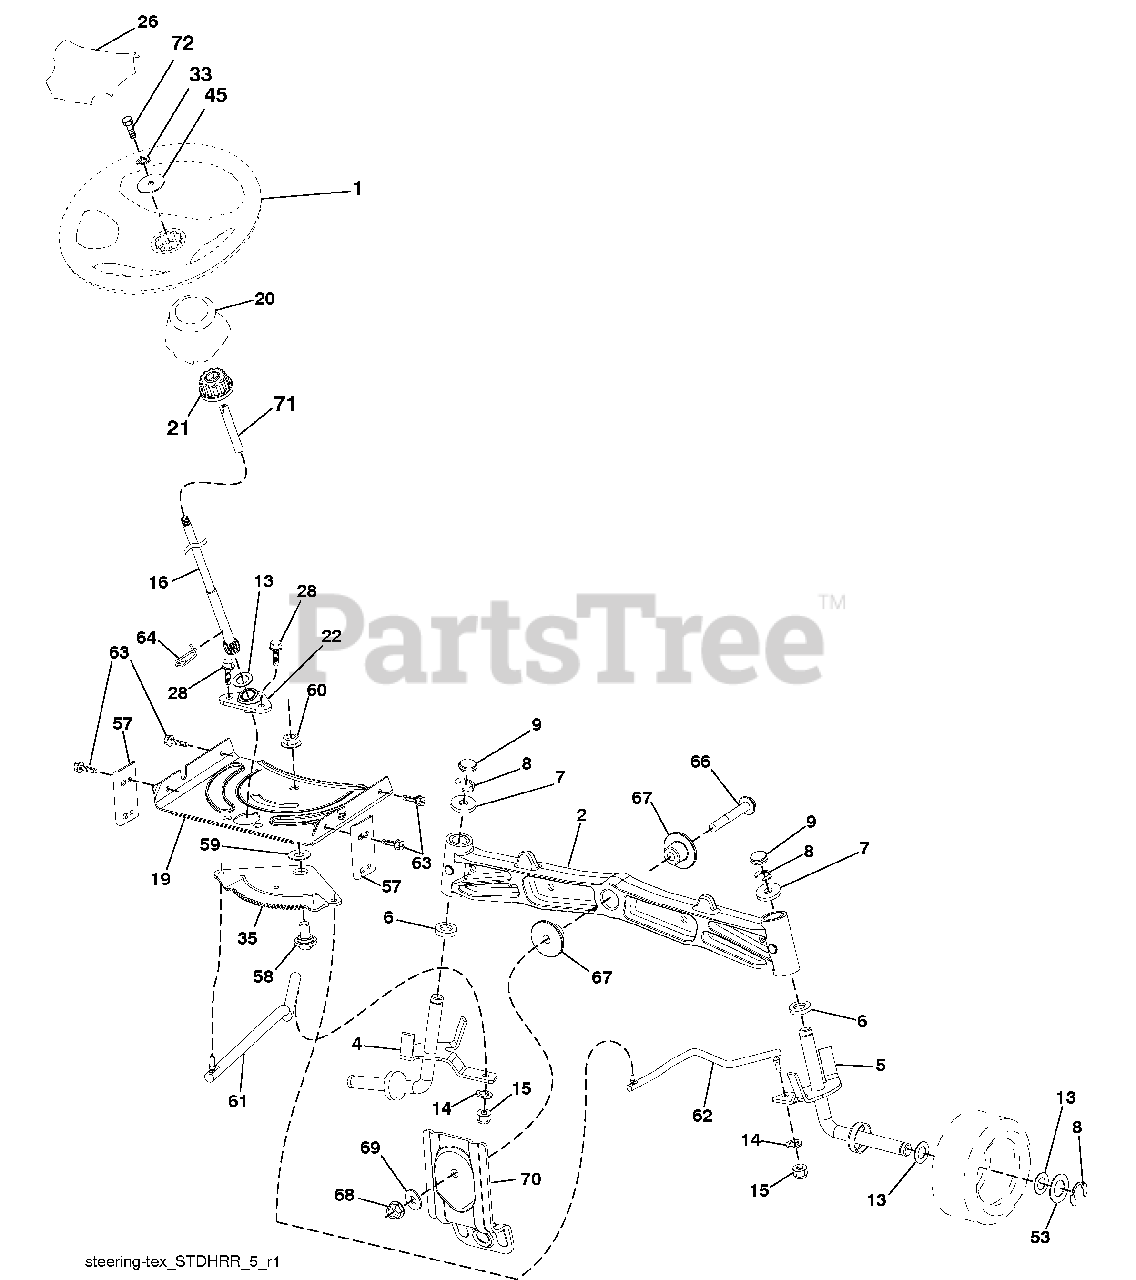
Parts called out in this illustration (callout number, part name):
1	Wheel, Steering
2	Axle Asm., Front
4	Spindle Asm., LH
5	Spindle Asm., RH
6	Bearing, Race Thrust Harden
7	Washer 25/32 x 1-5/8 x 16 Ga.
8	Ring, Klip #T5304-75
9	Cap, Spindle
13	Washer 25/32 x 1-1/4 x 16 Ga.
14	Washer, Lock Hvy Hlcl Spr 3/8
15	Nut, Crown Lock 3/8-24 unf
16	Shaft Steering
19	Plate Steering
20	Boot Steering
21	Adapter, Wheel Steering
22	Strg. Supt. Lower
26	Insert, Wheel Steering
28	Screw 3/8-16 x 3/4
33	Washer Lock Hvy HLCL SPR. 5/16
35	Gear, Sector Plate
45	Washer 11/32 ID x 2 3/8 OD x 12 Ga.
53	Washer Hardened .793 x 1.637 x .060
57	Bracket Upstop
58	Bolt Shoulder Sector Pivot CFM
59	Washer Thrust Sector Steering
60	Nut Flange Lock 5/8-11
61	Draglink, LH
62	Draglink, RH
63	Screw 5/16-18 x 3/4
64	Retainer Clip Spring Steering
66	Bolt Hex Fghd 7/16-14 x 3 Serr
67	Bushing PM Front Axle
68	Nut Lock Flange 7/16-14 Gr. 5
69	Washer 1.5 x .505 x .118
70	Bracket Deck Susp. Front
71	Shaft Exten. Strg.
72	Bolt Fin Hx. 5/16-18 x 4 w/Patch
